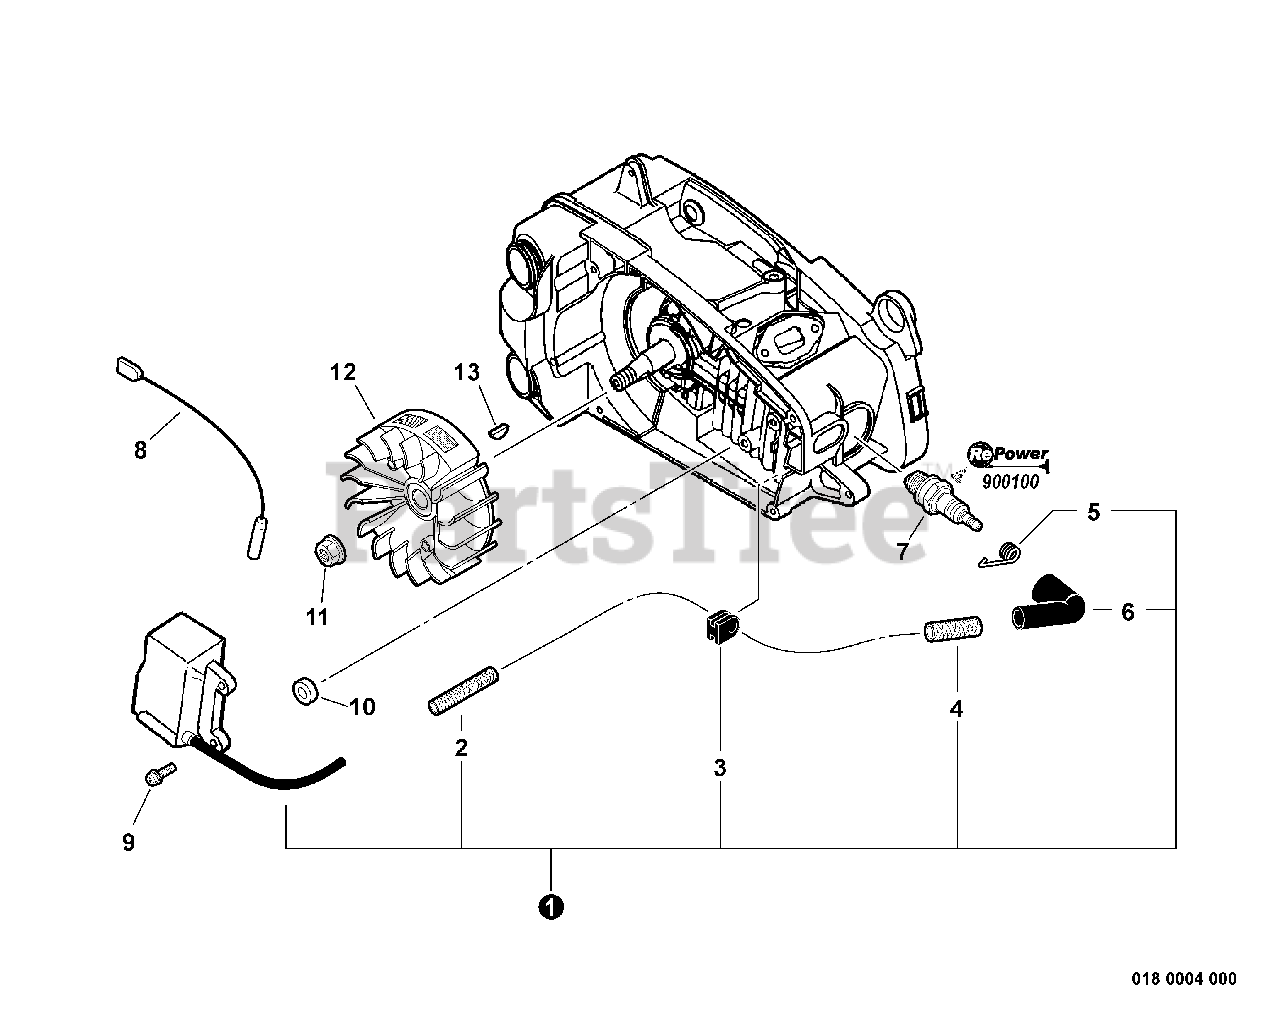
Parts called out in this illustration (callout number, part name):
1	COIL, IGNITION
2	TUBE, INSULATOR
4	TUBE, INSULATOR
5	CAP, SPARK PLUG
6	TERMINAL, SPARK PLUG CAP
7	SPARK PLUG -- BPM-8Y
7	SPARK PLUG -- BPMR-8Y
8	LEAD - IGNITION
9	SCREW - 5X22
11	NUT - 8 -- FLANGE
12	FLYWHEEL
14	RePower TUNE-UP KIT
